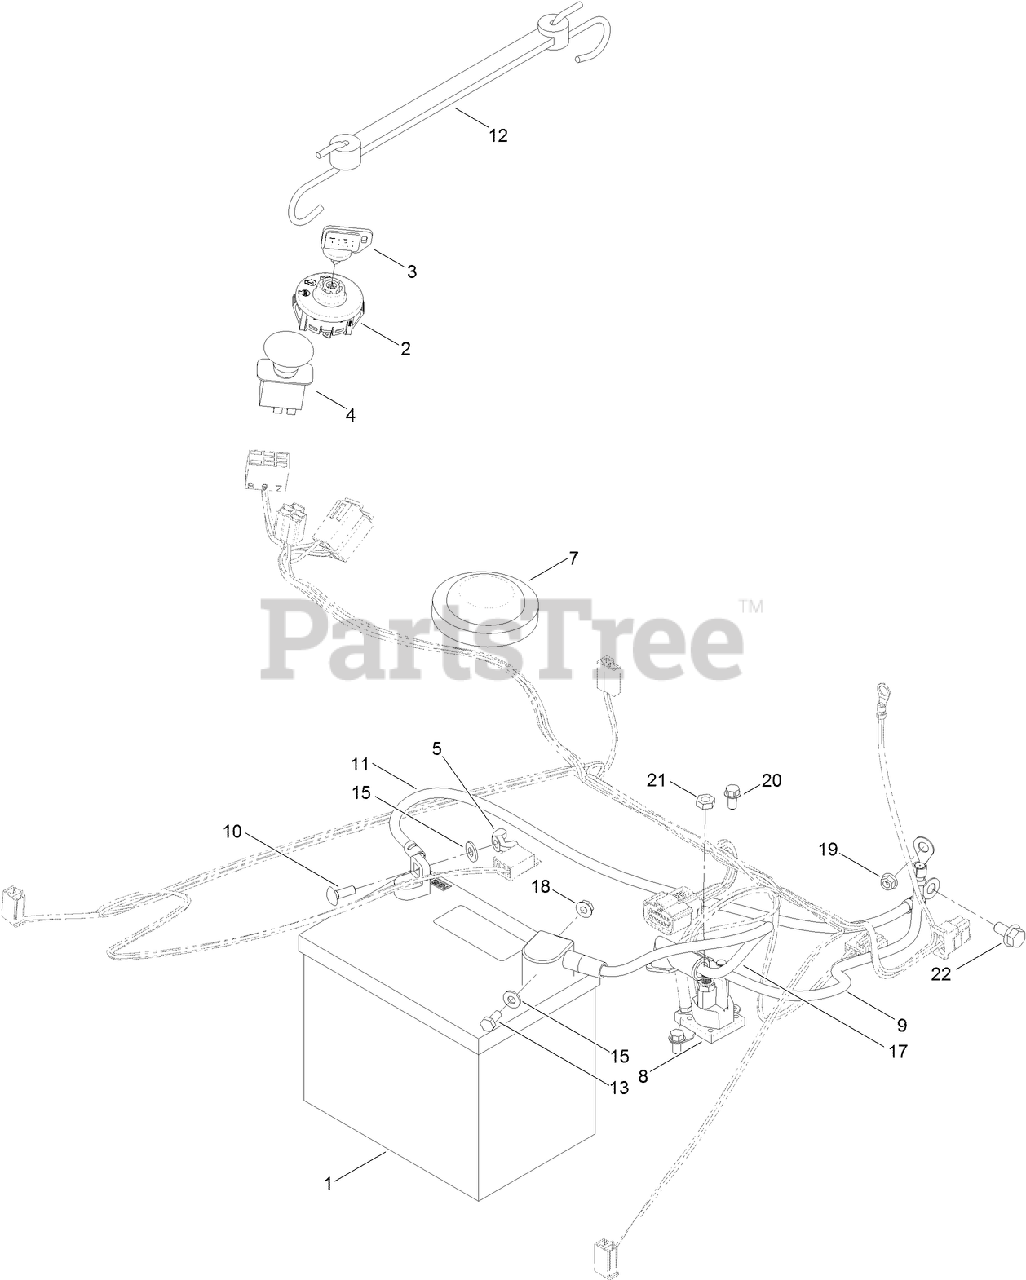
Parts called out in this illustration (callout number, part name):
1	BATTERY
3	KEY-IGNITION
4	SWITCH-PTO, ON-ON
5	NUT-WING
7	SWITCH-SEAT
8	SOLENOID
9	CABLE-BATTERY, POSITIVE
10	BOLT-CARR
11	CABLE-BATTERY, BLACK
12	HOLDDOWN-BATTERY
13	SCREW-HH
15	WASHER-FLAT
17	CABLE-BATTERY, RED
18	NUT-HF
19	NUT-HF
20	SCREW-HWH
21	NUT-JAM
22	SCREW-HHF
